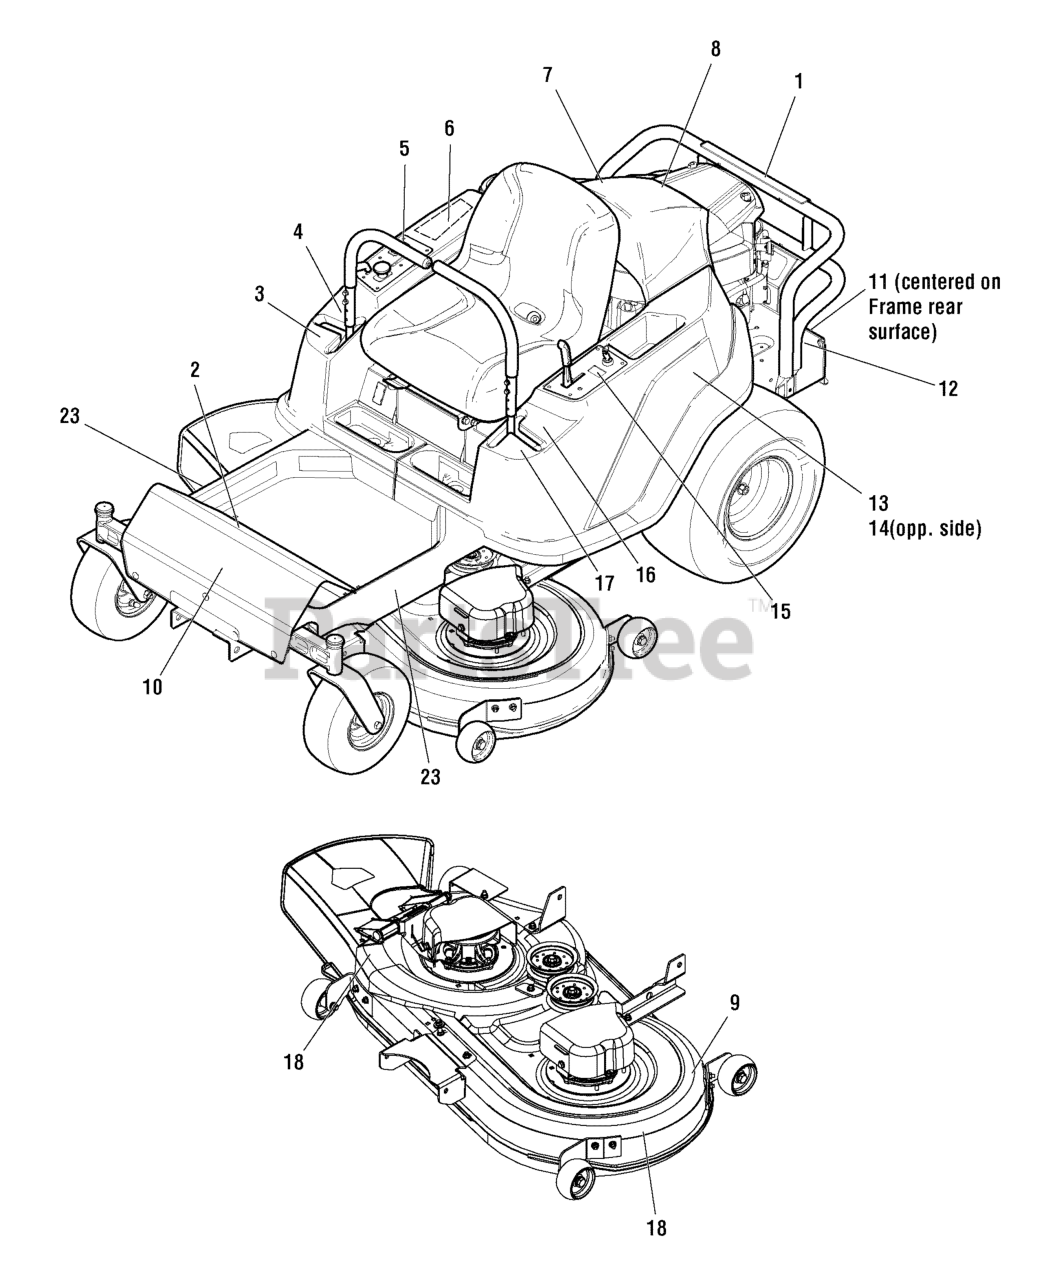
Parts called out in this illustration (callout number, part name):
1	DECAL, Rear, Craftsman ZTS
2	DECAL, DANGER, French, 285Z
3	DECAL, Handle, Ground Speed, RH, 285Z
4	DECAL, WARNING, English, RH 285Z
5	DECAL, Control Panel, RH 285Z
6	DECAL, DANGER, English, 285Z
7	DECAL, Release, Transaxle, 285Z
8	DECAL, Caution, Screen Rotating
9	DECAL, 42" Deck
10	DECAL, Model, Craftsman ZTS
11	DECAL, Weight Limitation
12	DECAL, WARNING Burn Hazard
13	DECAL, LH Fender, Craftsman ZTS
14	DECAL, RH Fender, Craftsman ZTS
15	DECAL, Control Panel, LH 285Z
16	DECAL, WARNING, French, LH 285Z
17	DECAL, Handle, Ground Speed, LH, 285Z
18	DECAL, DANGER Do Not Operate w/o Deflector
23	DECAL, DANGER, Amputation Risk
